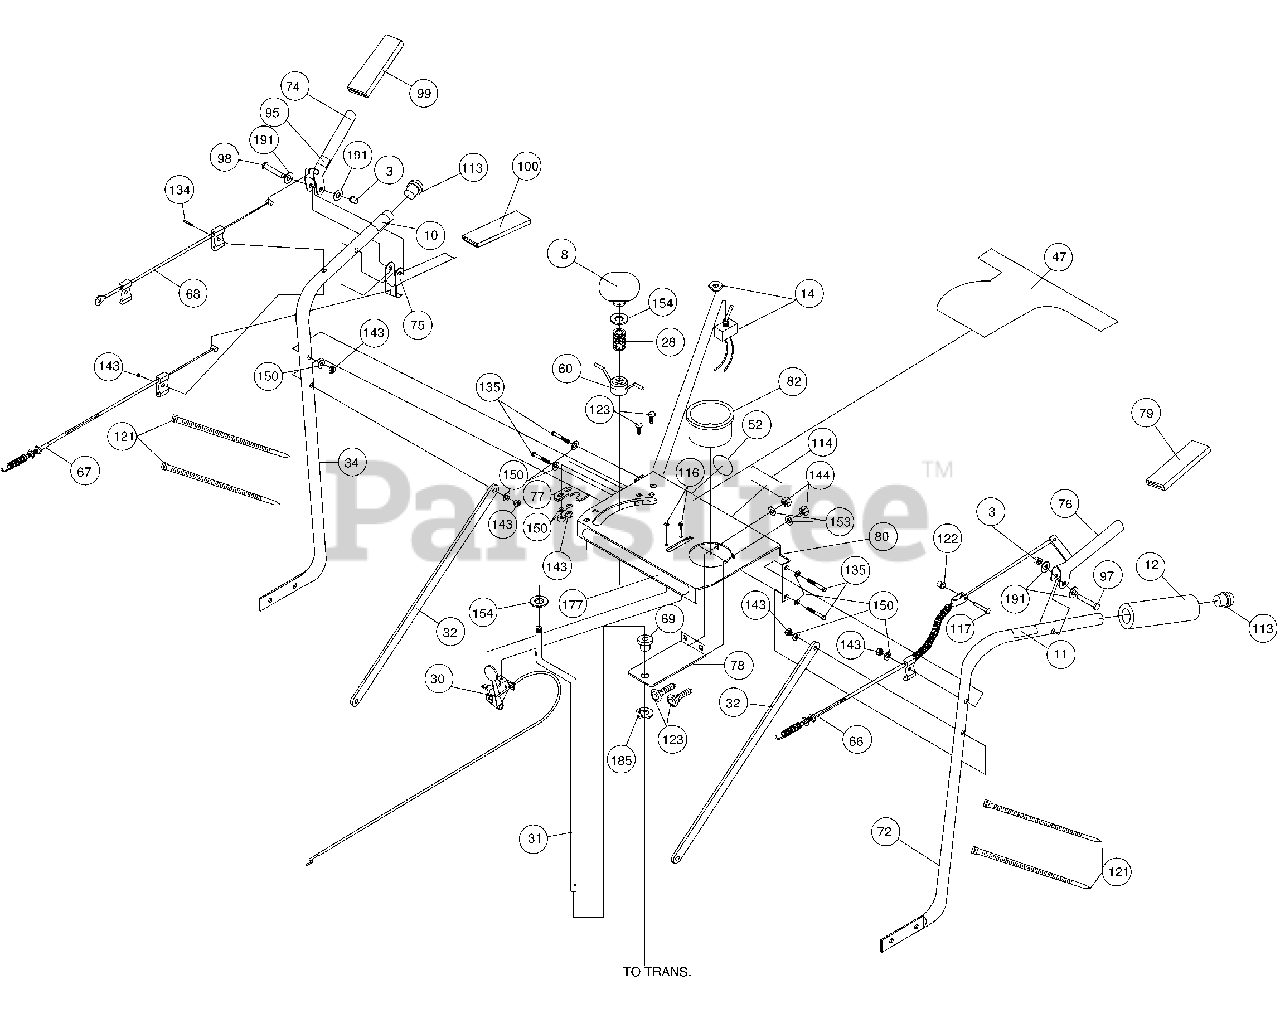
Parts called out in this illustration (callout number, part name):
3	PALNUTS 3/8”
8	KNOB 1/2” THREAD
10	LABEL CLUTCH DRIVE
11	LABEL BLADE DRIVE
12	GRIP HANDLE 1” x 7”
14	SWITCH ELECTRIC W/ NUT
28	SPRING COMPRESSOR 1/2”
30	CONTROL THROTTLE POS
31	ROD SHIFT LINKGAGE
32	BAR HANDLE BRACE FM
34	HANDLE RH FM
47	LABEL CONSOLE
52	LABEL READ MANUAL
60	SHIFT LOCK HANDLE FM WA
66	CABLE CLUTCH BLADE FM
67	CABLE CLUTCH DRIVE FM
68	CABLE CLUTCH BRAKE FM
69	BUSHING NYLON
72	HANDLE LH FM
74	LEVER CONTROL BRAKE FM
75	LEVER CONTROL DRIVE FM
76	LEVER CONTROL BLADE FM
77	PLATE REV LOCK OUT
78	BRACKET SHIFT PIVOT FM
79	GRIP LEVER ORANGE
80	CONSOLE FM W/ LABELS
82	CUP HOLDER
86	BRAKE PUCK FM
95	LABEL PUSH TO RELEASE
97	CLEVIS PINS 3/8 - 1.625
98	CLEVIS PINS 3/8 - 2.125
99	GRIP LEVER 0.125-1.00-3.75
100	GRIP LEVER 0.125-0.75X3.75
113	PLUG TUBE INSERT 1”
114	LABEL EAR-EYE-BREATHE
116	SCREW 1/4” - 20 X 5/8
117	PIN CLEVIS 5/16-24
122	PAL NUTS 5/16”
123	BOLT CARRIAGE 5/16-18 X 3/4
134	SCREW CAP 5/16-18 X 2
135	SCREWCAP 5/16-18 x 2 1/4
143	NUT LOCK 5/16-18 NYLON
144	NUT LOCK 3/8-16 NYLON
150	WASHER 1/4” FC
153	WASHER 5/16 SAE
154	WASHER 1/2” SAE ZP
177	LABEL BGI OVAL FM
185	RETAINING RING EXTERNAL
191	WASHER 5/16” FC
